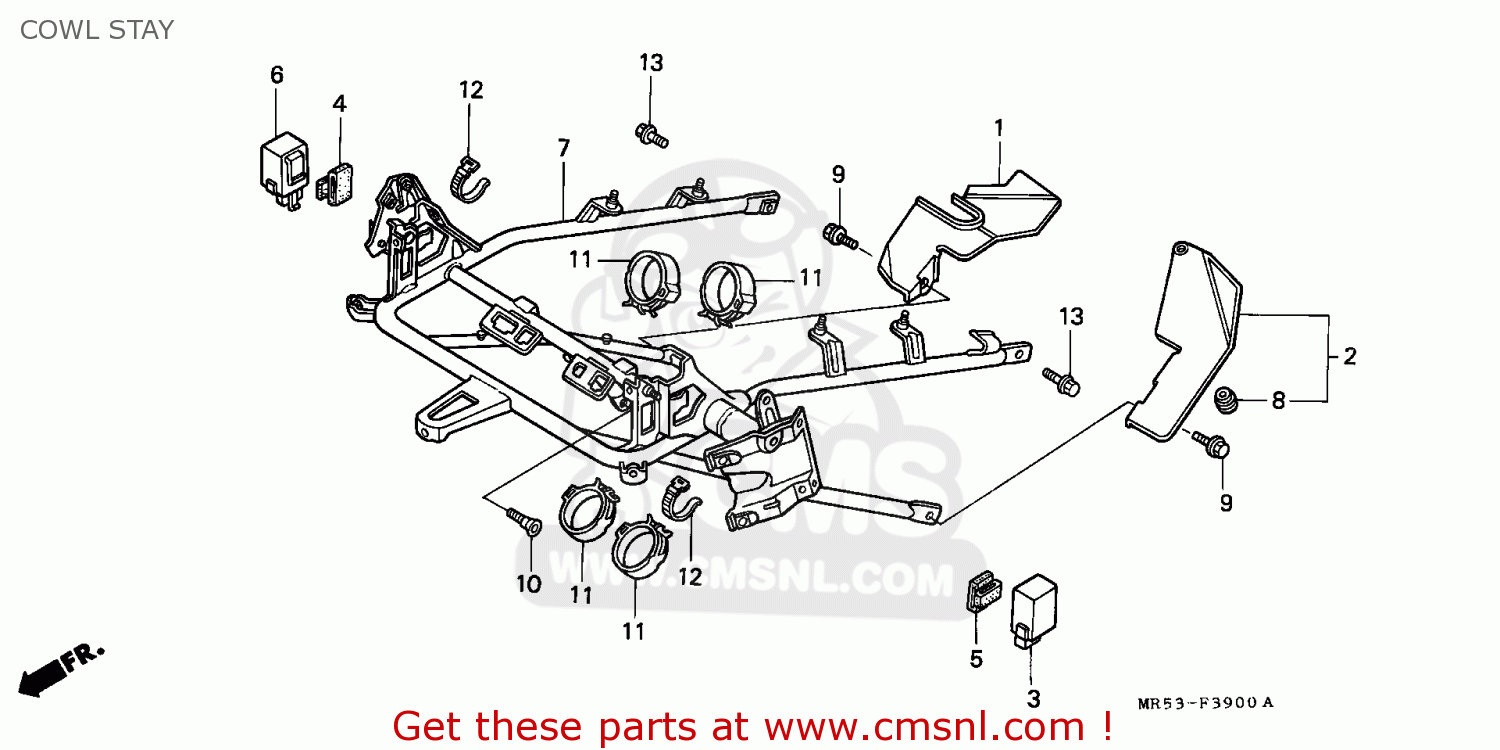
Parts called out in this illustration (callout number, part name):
3	RELAY COMP,WINKER
4	SUSPENSION,RELAY
5	SUSPENSION,WINKER
6	RELAY,POSITION
7	STAY COMP COWL
9	BOLT,FLANGE,6X12
10	SCREW,FLAT(SOCICE
11	CLIP,CABLE,25MM
12	BAND B3,WIRE HARN
13	BOLT,FLANGE.8X16
